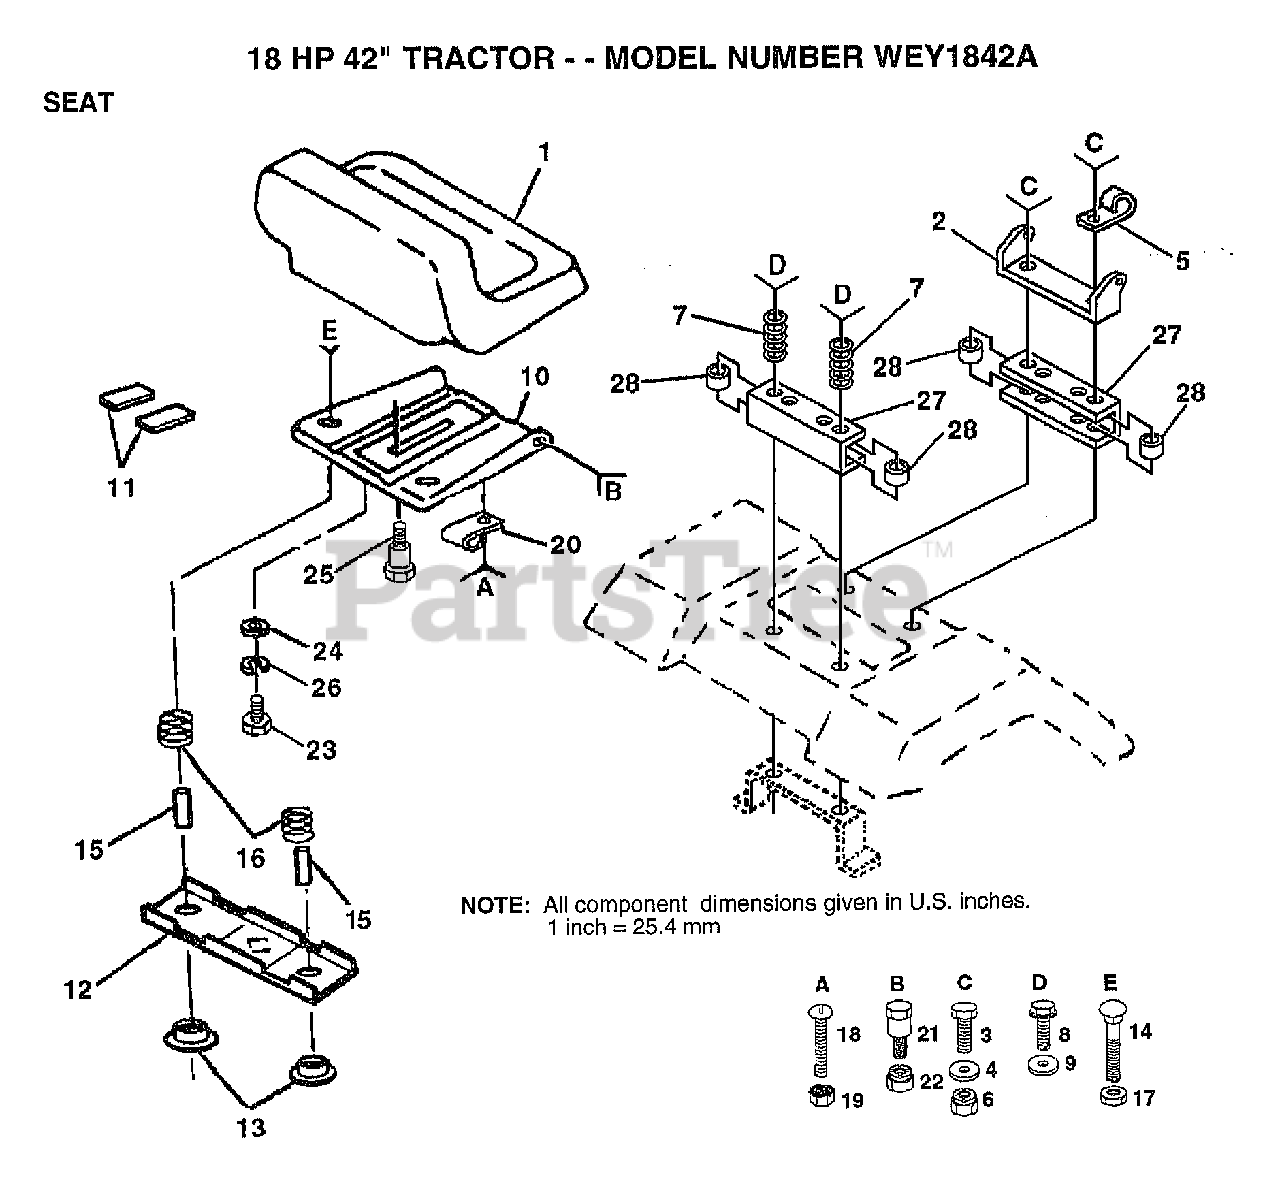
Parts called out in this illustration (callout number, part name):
3	BOLT
4	WASHER PM
5	CLIP T
7	SPRING COMPRESSIO
8	SCREW
9	WASHER
11	STRIP FORM
12	BRKT SWITCH
13	BUSHING
15	SPLIT SPACER
16	SPRING
19	"NUT,KEPS"
23	BOLT
24	WASHER
25	"BOLT,SHOULDER"
26	LOCKWASHER
27	SEAT SPACER
28	SPLIT SPACER
